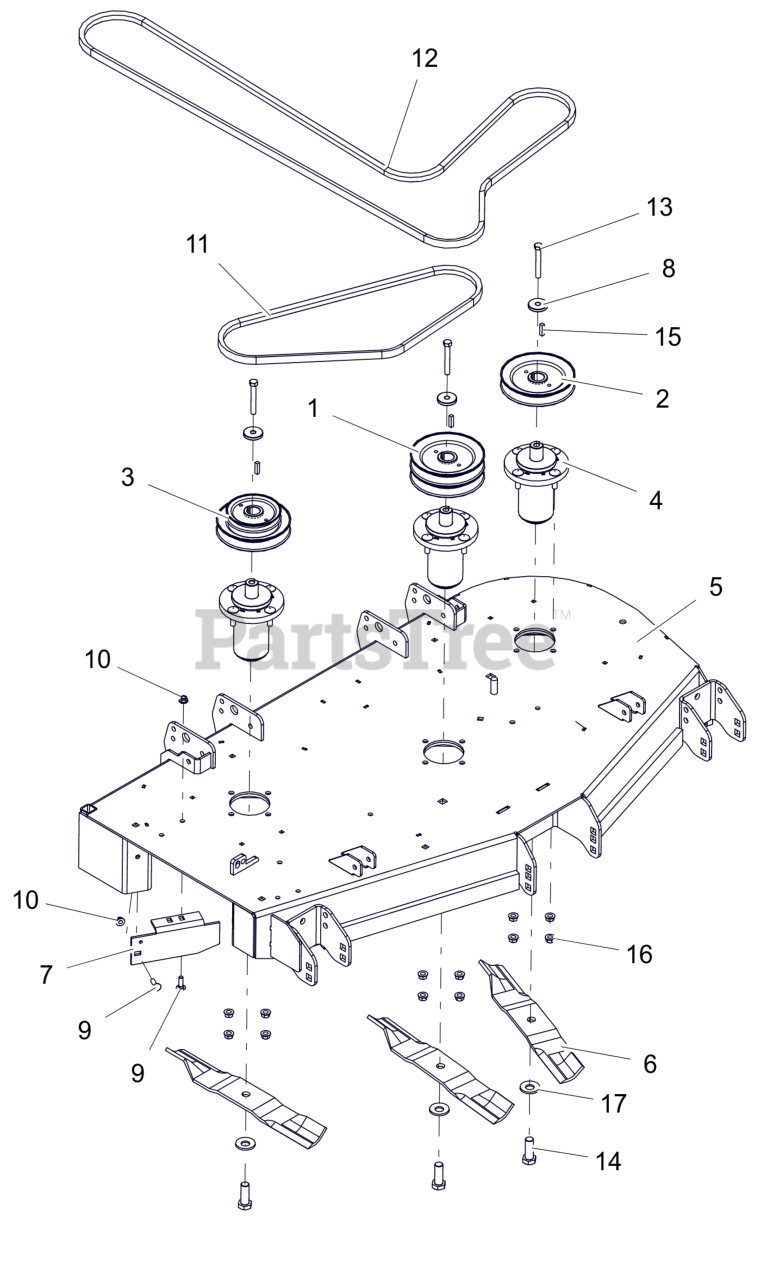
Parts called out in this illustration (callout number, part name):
1	PULLEY, DOUBLE 1.000 ID X 5.750 OD
2	PULLEY, V - 1.000 ID X 5.750 OD
3	PULLEY, DBL-1"IDX5.75"&4.25"OD
4	ASM, MAINT FREE ALUM SPINDLE
5	WLDMT, PT148 SIDE DISCH DECK (RED)
6	BLADE, 16.19" MOWER (HI-LIFT)
7	44"-48" SIDE DISCH BAFFLE -RED
8	RETAINER, SHEAVE
9	BLT,RHSN .31-18X1.00 G5 ZCC
10	NUT,NYL-FLG .31-18 GF ZCC
11	V-BELT, B-COGGED
12	V-BELT, B RAW EDGE EPDM
13	BLT, HEX .38-16X2.75 G8 ZCC
14	BLT, HEX .62-18X1.75 G8 ZCC
15	KEY, SQ .25X.25X1.00 RC 40-50
16	NUT-LK-CTR-FLG .375-16 GF ZCC
17	WSHR-BLVL .669X1.535X.138
